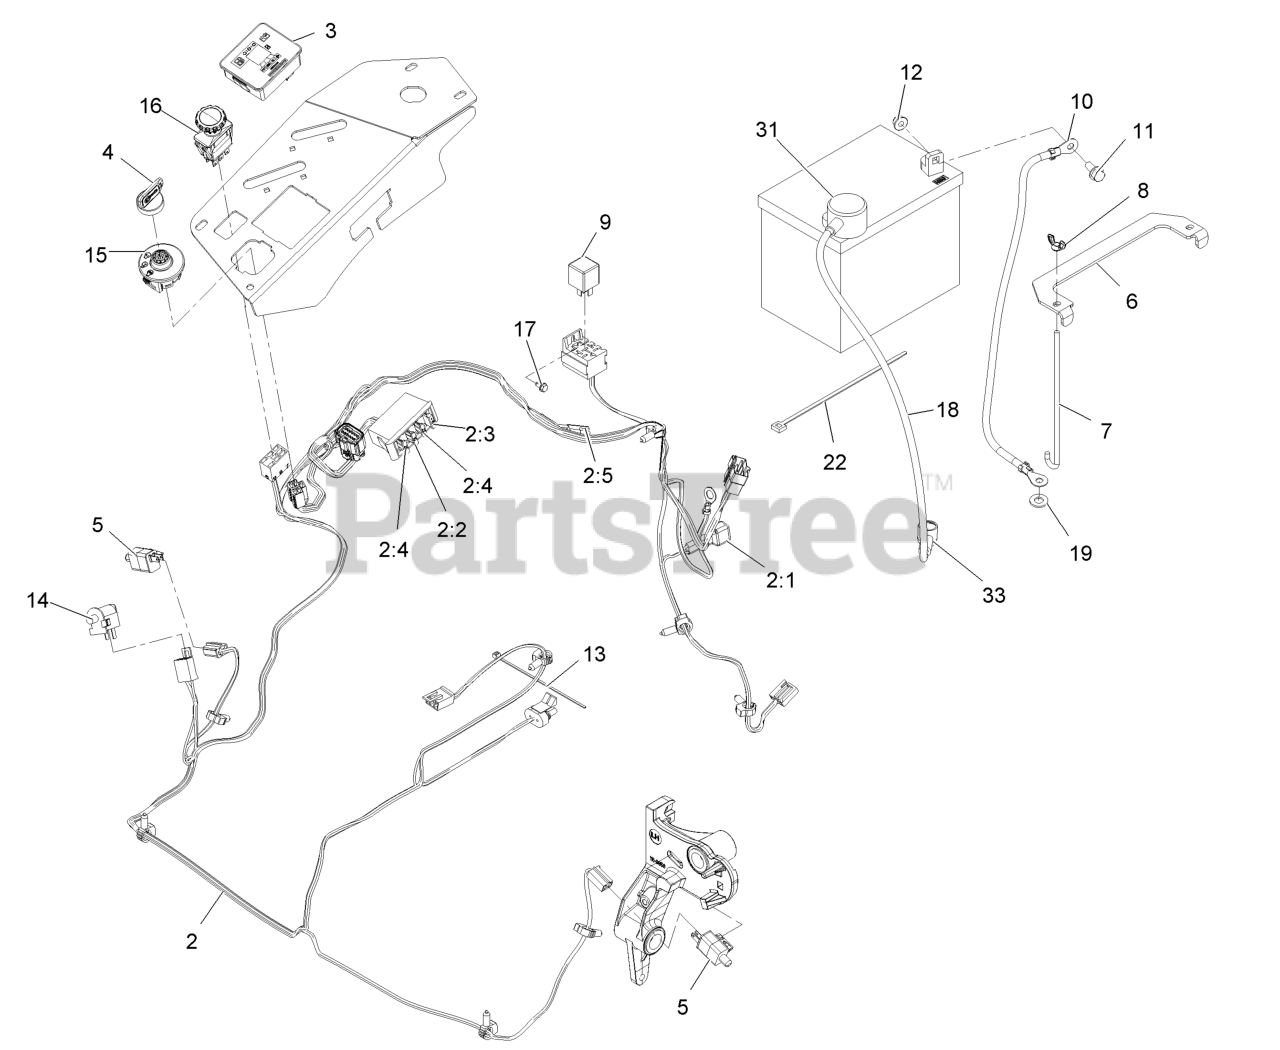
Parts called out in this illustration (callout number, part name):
2:2	FUSE-BLADE, 10 AMP
2:3	FUSE-BLADE, 15 AMP
2:4	FUSE-BLADE, 25 AMP
2:5	CAP-PLUG
3	FUEL/HOUR METER ASM
4	KEYS-IGNITION (SPARE PAIR
4	KEY-IGNITION
6	STRAP-TIE DOWN, BATTERY
7	BOLT-HOLDDOWN
8	WINGNUT
10	CABLE-BATTERY, NEGATIVE
11	SCREW-HHF
12	NUT-HF, NI
13	TIE-CABLE
14	SWITCH-BAIL
16	SWITCH-PTO, 10 AMP
17	SCREW-HWH
18	CABLE-BATTERY, POSITIVE
19	WASHER-FLAT
22	TIE-PLASTIC
31	INSULATOR-BATTERY
33	INSULATOR-SOLENOID
